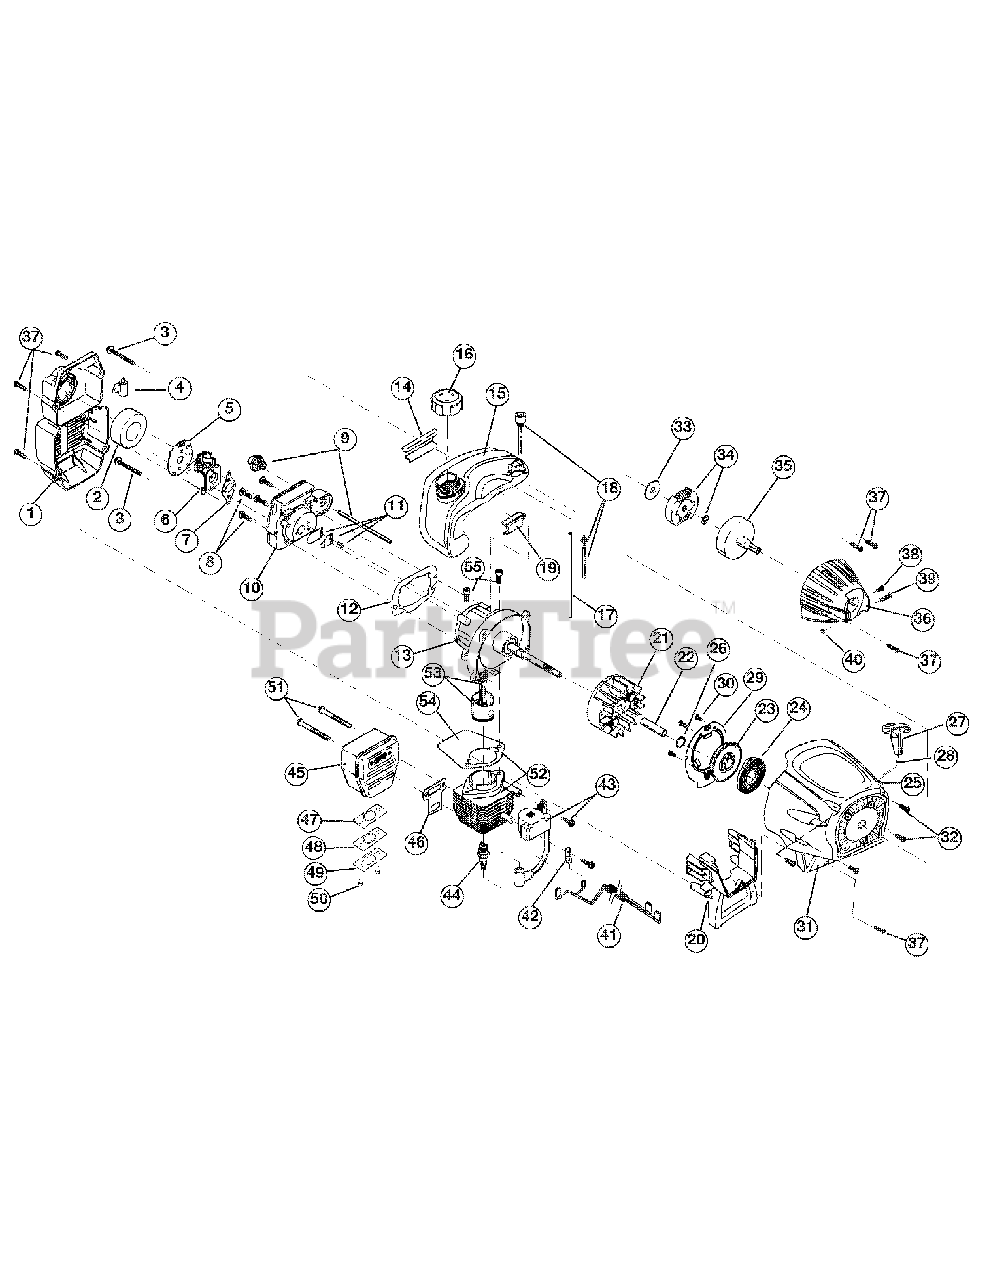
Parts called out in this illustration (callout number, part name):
1	Air Cleaner Cover Assembly (includes 2 & 37)
2	Air Cleaner Filter
3	Carburetor Mounting Screw Assembly
4	Choke Extension
5	Choke Plate
6	Carburetor Assembly (includes 7 & 18)
7	Carburetor Gasket
8	Carb Mount Screw
9	Primer & Hose Assembly
10	Carb Mount Assembly (includes 8, 11 & 12)
11	Reed Assembly
12	Carburetor Mount Gasket
13	Crankcase Service Assembly (includes 8)
14	Rear Mounting Pad
15	Fuel Tank Assembly (includes 16-18)
16	Fuel Cap Assembly
17	Fuel Return Line
18	Fuel Line Assembly
19	Front Mounting Pad
20	Shroud Extension & Stand
21	Flywheel Assembly
23	Recoil Pulley Assembly (includes 24, 26 & 28)
24	Recoil Spring
25	Rope Guide
26	Pulley Retainer
27	Pull Handle
29	Pressure Plate Assembly
30	Plate Screw
31	Starter Housing Assembly(includes 23-30, 32 & 37)
32	Housing Screw
33	Clutch Washer
34	Clutch Rotor Assembly
35	Clutch Drum Assembly
36	Clutch Cover Assembly (includes 37-40)
37	Cover Screw
38	Anti-Rotation Screw
39	Clamping Screw
40	Clamping Nut
41	Wire Leads and Sleeve
42	Ground Tab
43	Module Assembly (includes 42)
45	Muffler Assembly (includes 46-51)
46	Exhaust Gasket
47	Spark Arrestor Screen
48	Exhaust Hood Diverter
49	Exhaust Hood
50	Screws
51	Muffler Mounting Bolts
52	Cylinder Assembly (includes 54 & 55)
53	Piston and Rod Assembly
54	Cylinder Gasket
55	Cylinder Bolt
